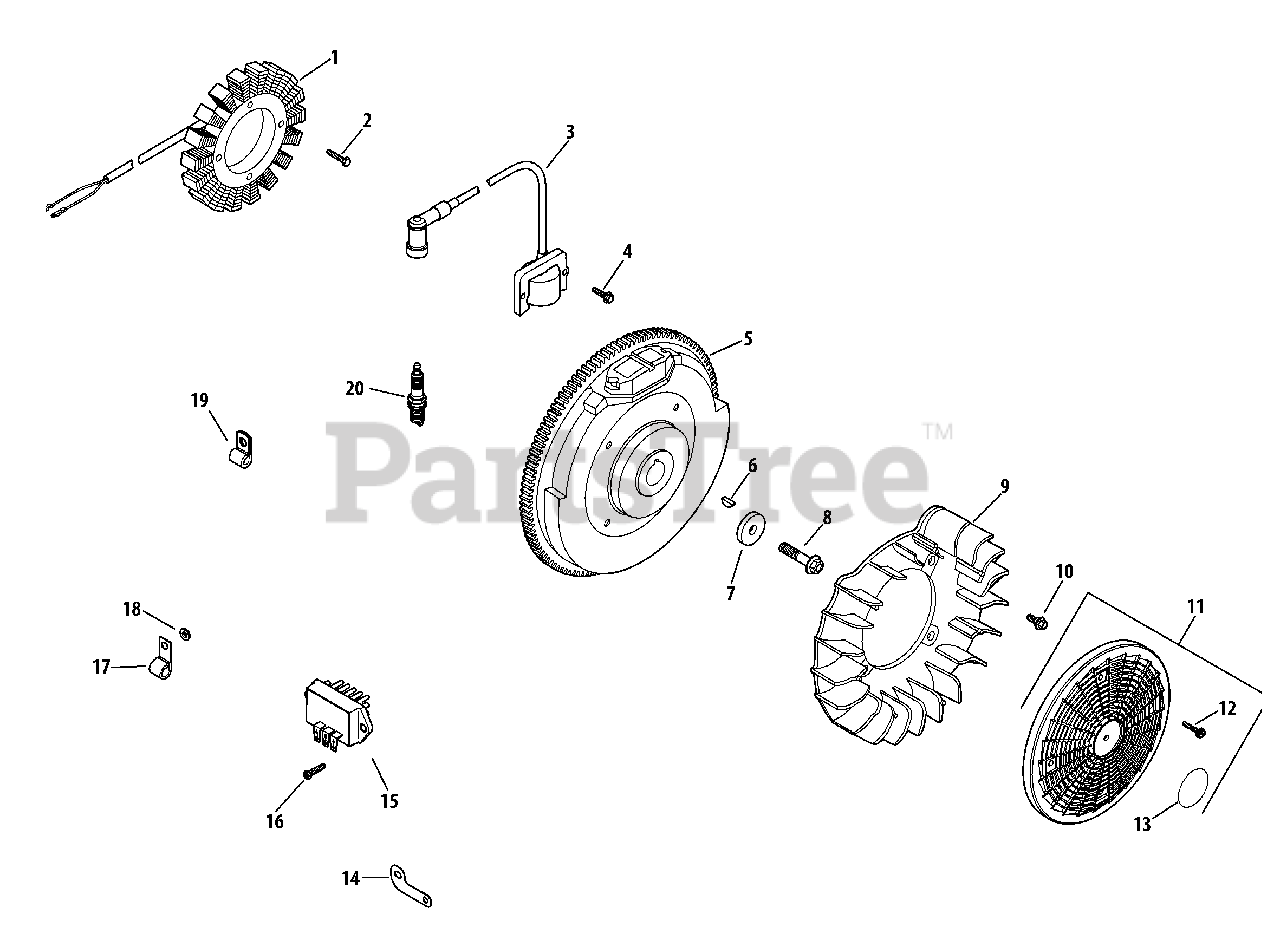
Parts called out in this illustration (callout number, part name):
1	15/20 Amp Stator Kit
2	Screw, M5 x 0.8 x 25
3	Ignition Module Kit (CDI Fixed)
4	Flange Screw, M5 x .8 X 20
6	Key, 3/16 X 5/8
7	Flat Washer, 13/32
8	Flange Screw, M10 x 1.5 x 45
10	Shoulder Bolt
11	Grass Screen Kit
12	Flange Screw, M4 x .7 X 25
13	Grass Screen Decal
14	Ground Strap Bracket
15	Rectifier Regulator
16	Hex Flange Screw
17	Cable Clip
18	Flat Washer, 1/4 x 1/2
20	Spark Plug (Standard)
